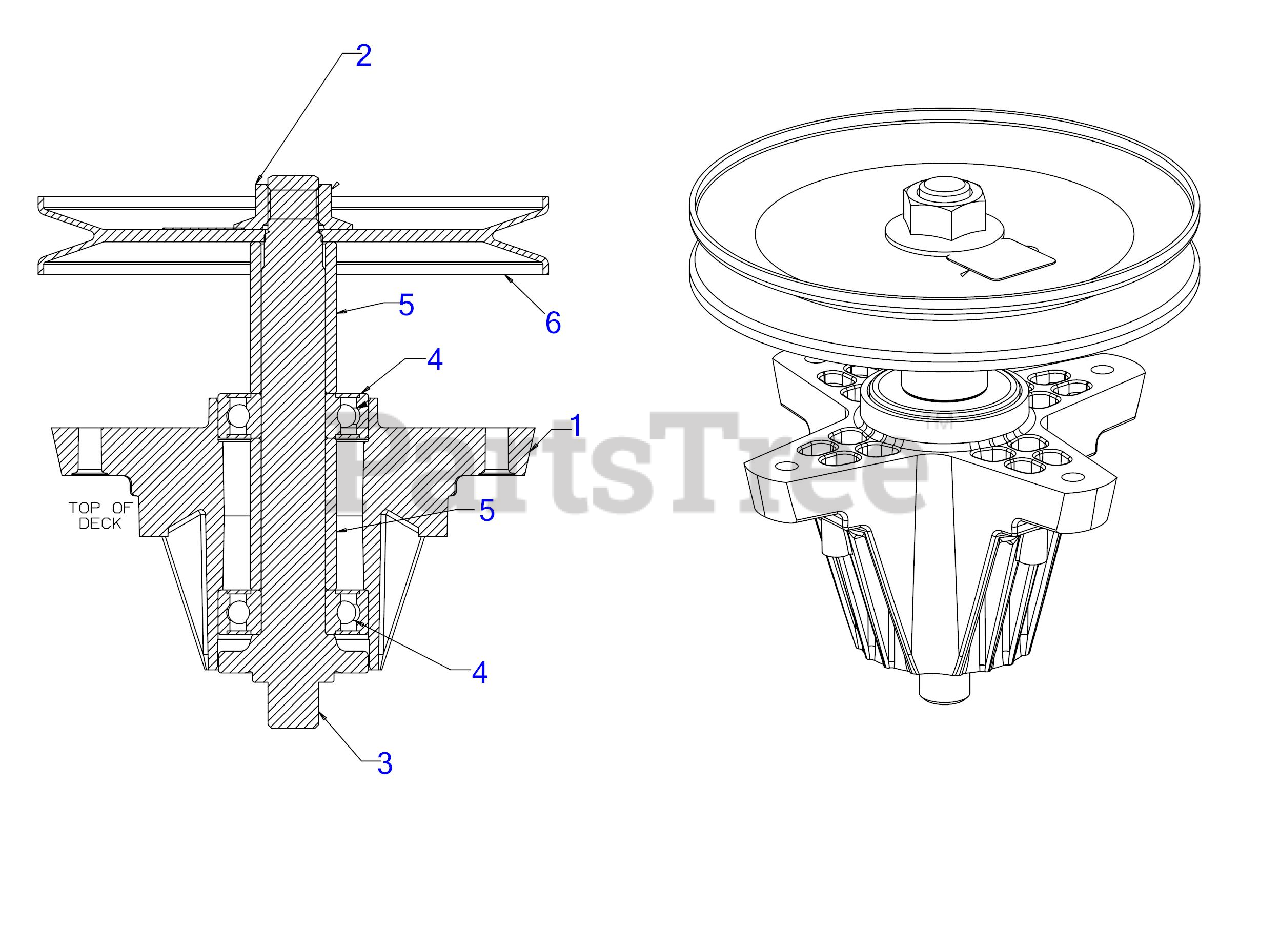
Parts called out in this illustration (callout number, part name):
1	DECK SPINDLE HOUSING
2	FLANGE NUT 5/8-18
3	BLADE SPINDLE SHAFT STAR 6.11 LG
4	BALL BEARING
5	SPACER- .792 x 1.060 x 1.860
6	DECK PULLEY 6.74" DIA
